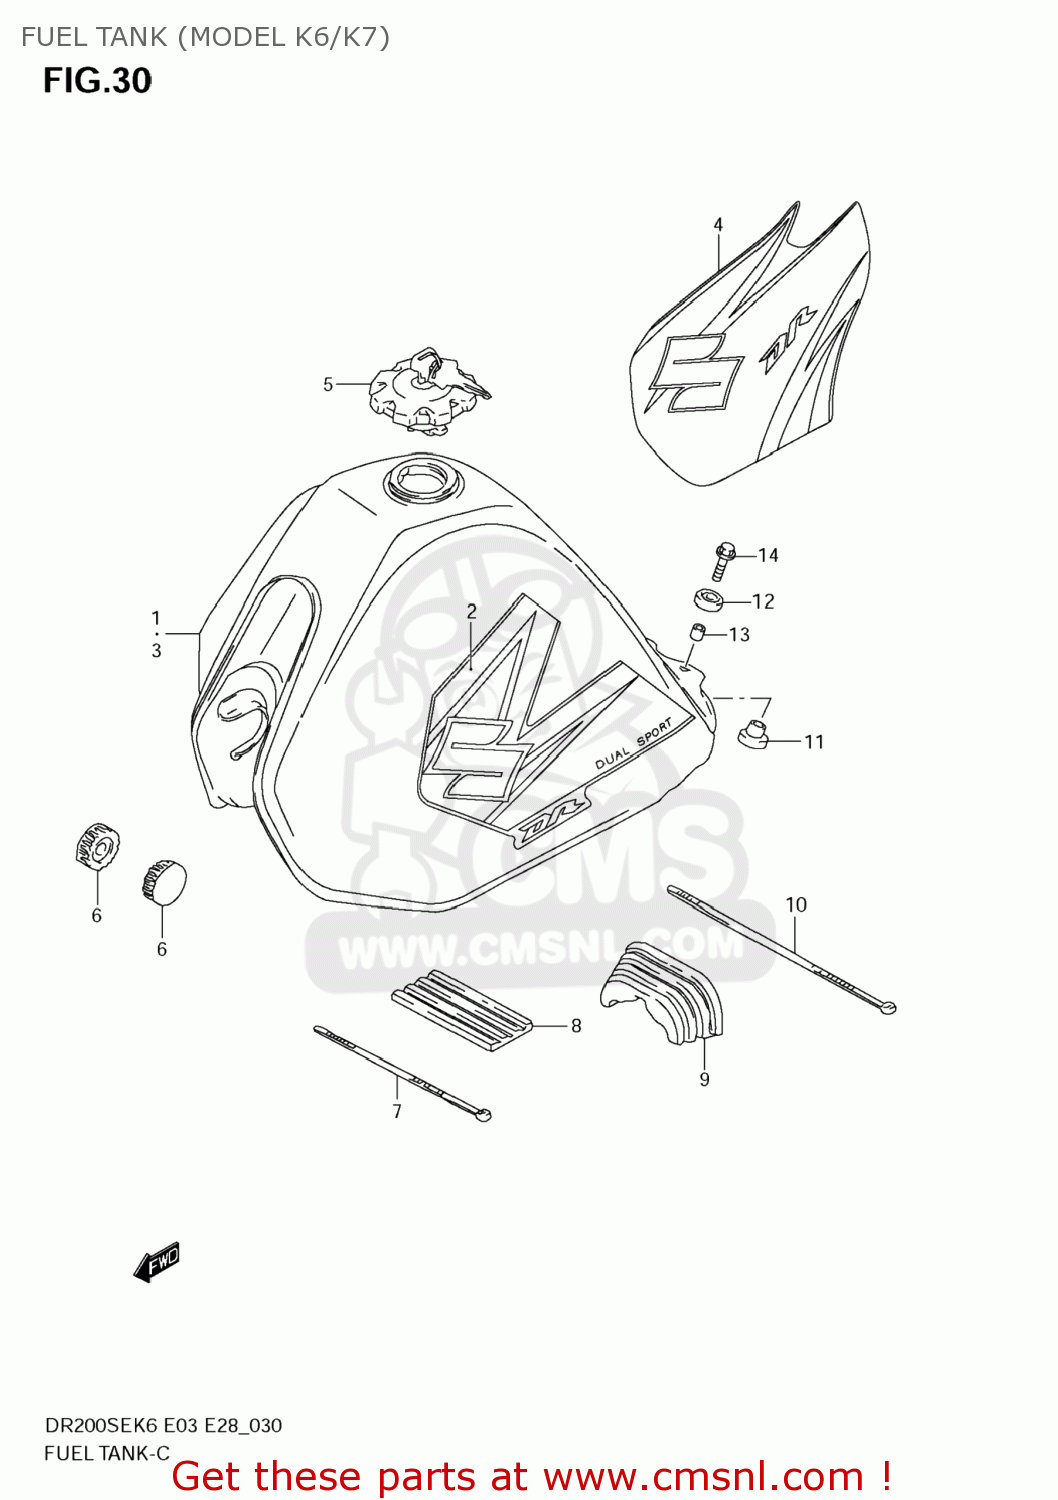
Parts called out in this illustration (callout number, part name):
1	TANK ASSY,FUEL(BLUE)
2	TAPE SET,FUEL TANK
3	TANK ASSY,FUEL(BLUE)
4	TAPE SET,FUEL TANK
5	CAP SET,FUEL TANK
6	CUSHION
7	CLAMP(L:250)
8	CUSHION,FUEL TANK UPR FR
9	CUSHION,FUEL TANK RR
10	CLAMP(L:300)
11	CUSHION
12	CUSHION
13	SPACER(6.5X9X18)
14	BOLT
